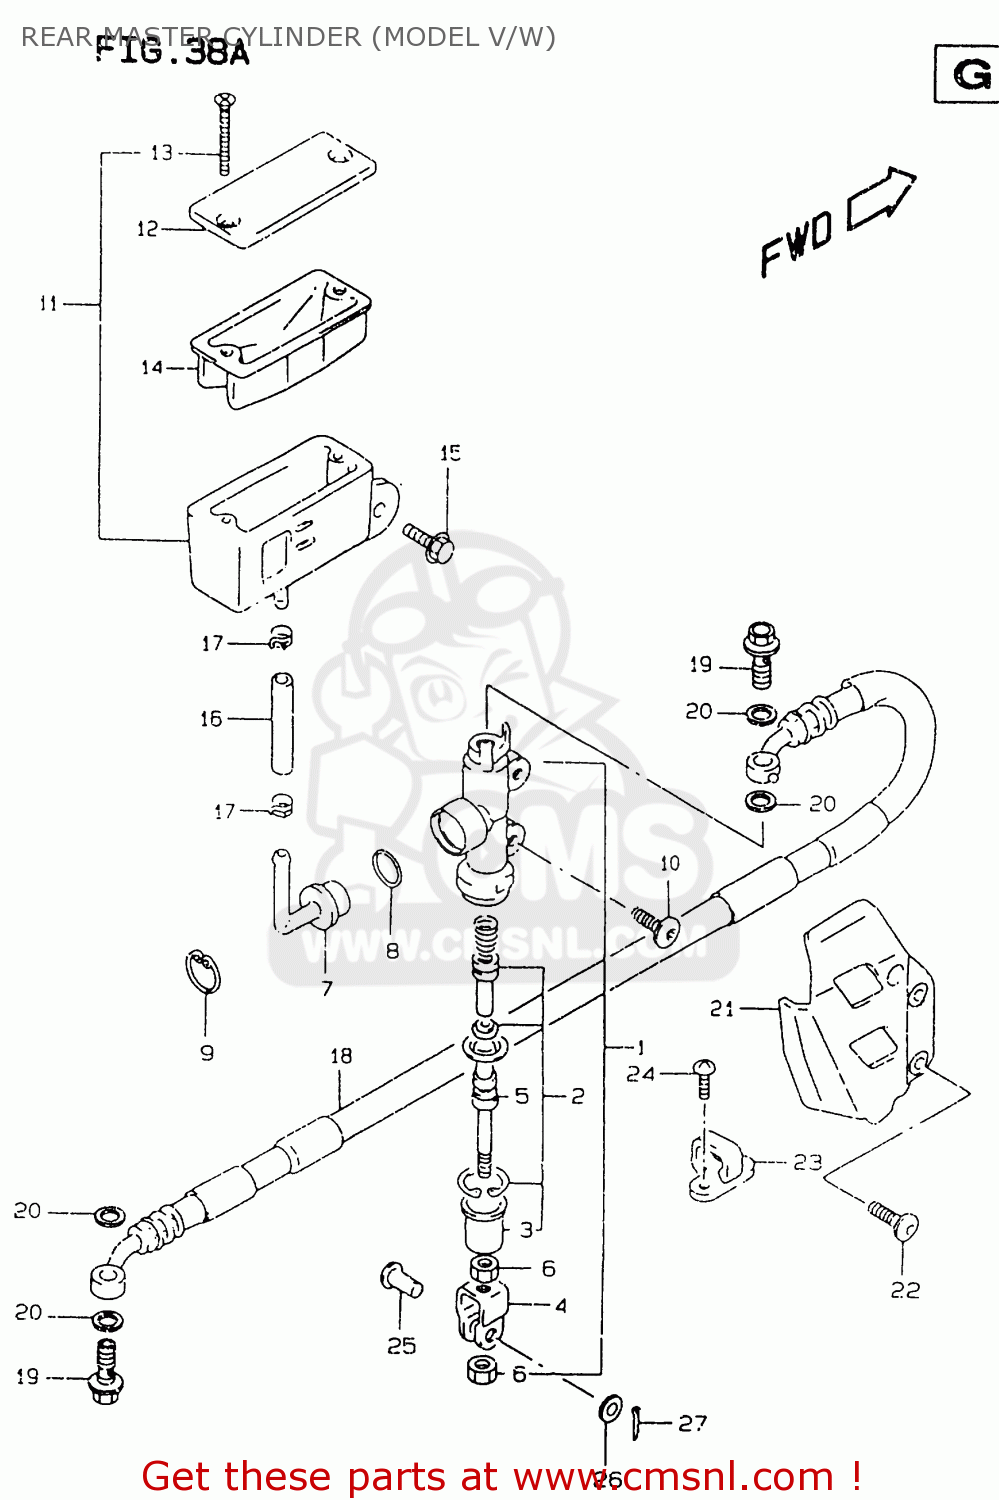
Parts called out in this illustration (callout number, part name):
1	CYLINDER ASSY,RR MASTER
2	PISTON/CUP SET
3	BOOT
4	YOKE
5	ROD,PUSH
6	NUT
7	CONNECTOR
8	O RING
9	CIRCLIP
10	SCREW(6X16)
11	TANK ASSY,RESERVOIR
12	CAP
13	SCREW
14	DIAPHRAGM
15	BOLT
16	HOSE,RESERVOIR TANK
17	CLAMP,RESERVOIR HOSE
18	HOSE COMP,REAR BRAKE
19	BOLT UNION
20	WASHER(10X15X1.5)
21	GUARD,RR MASTER CYLINDER
22	SCREW(6X16)
23	GUIDE,RR BRAKE
24	SCREW
25	PIN(8X20)
26	WASHER(8.5X13X1.6)
27	PIN
